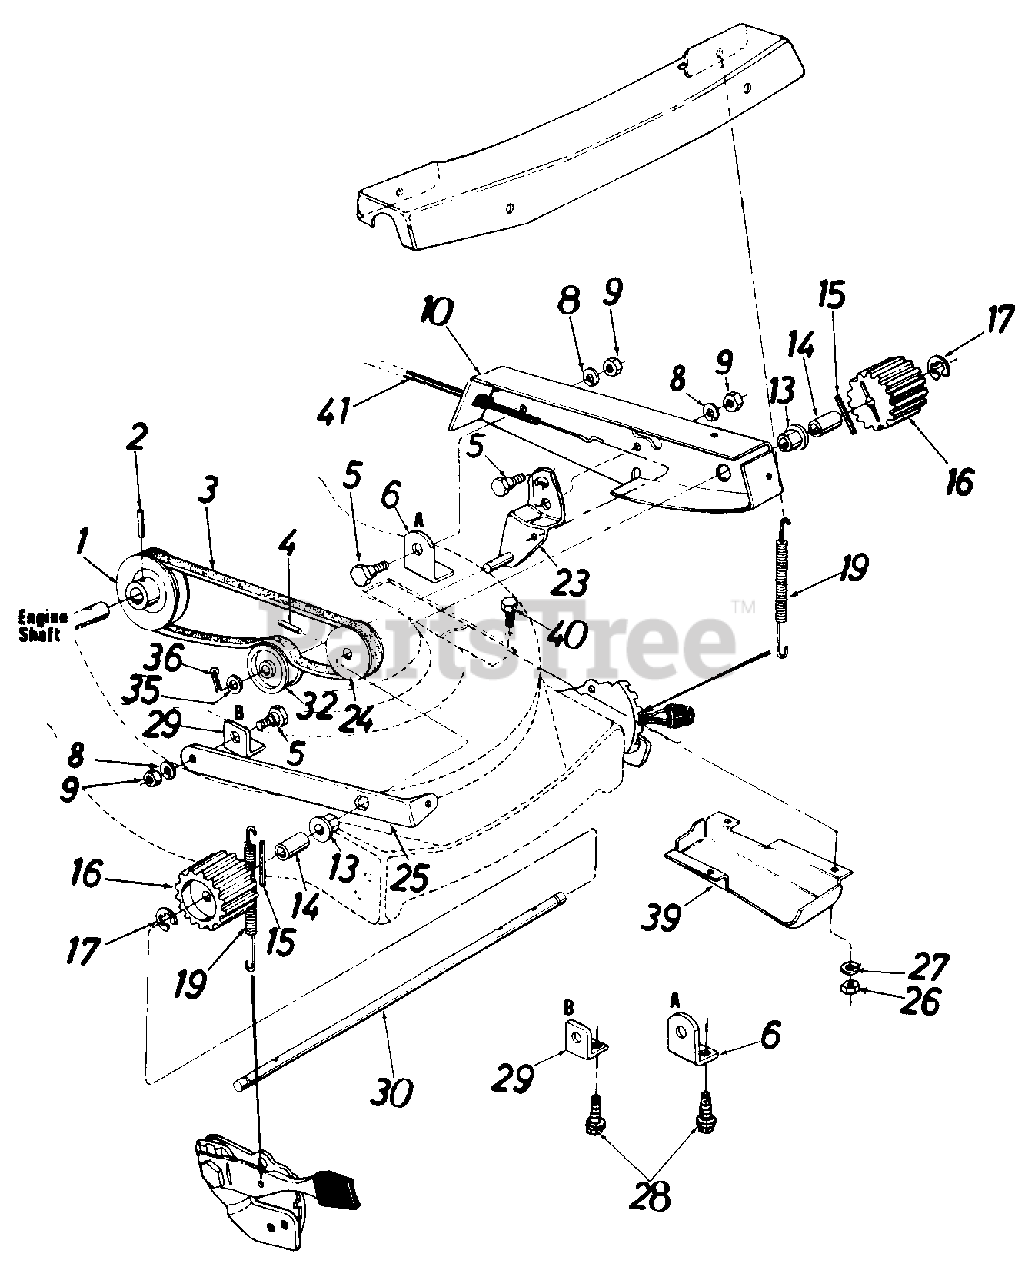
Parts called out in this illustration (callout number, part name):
1	1/2 "V"-Engine Pulley
2	Spring Pin Spiral 3/16" Dia. x 1.25" Lg.
3	"V"-Belt 1/2" x 28.0" Lg.
4	Spring Pin Spiral 3/16" Dia. x 1.00" Lg.
5	Shld. Bolt .500 Dia. x .170
6	Belt Cover Pivot Brkt.
8	L-Wash. 3/8" I.D.
9	Hex Jam Nut 3/8-16 Thd.
10	Belt Cover Ass'y
13	Hex Flange Brg. .503 I.D.
14	Spacer .52 I.D. x .69 O.D.
15	Spring Pin Spiral 3/16 Dia. x 1.25" Lg.
16	13 Teeth Drive Pinion
17	"E"-Ring for .500 Dia. Shaft
19	Extension Spring-3.25"
23	Idler Brkt. Ass'y.
24	1/2"V"-Pulley
25	Cover Support Brkt.
26	Hex Nut 1/4-20 Thd.
27	L-Wash. 1/4" I.D.
28	Hex Wash. Hd. Self-Tap Scr. 1/4 -20 x .50" Lg.
29	Cover Support Pivot Brkt.
30	Pinion Shaft
32	Plastic Flat Idler
35	Fl-Wash. .53 I.D. x .93 O.D.
36	Cotter Pin 1/8" Dia. x 1.0"
39	Belt Cover Baffle
40	Truss Mach. Scr. 1/4-20 x .50" Lg.
41	S.P. Cable-53"-Yellow
